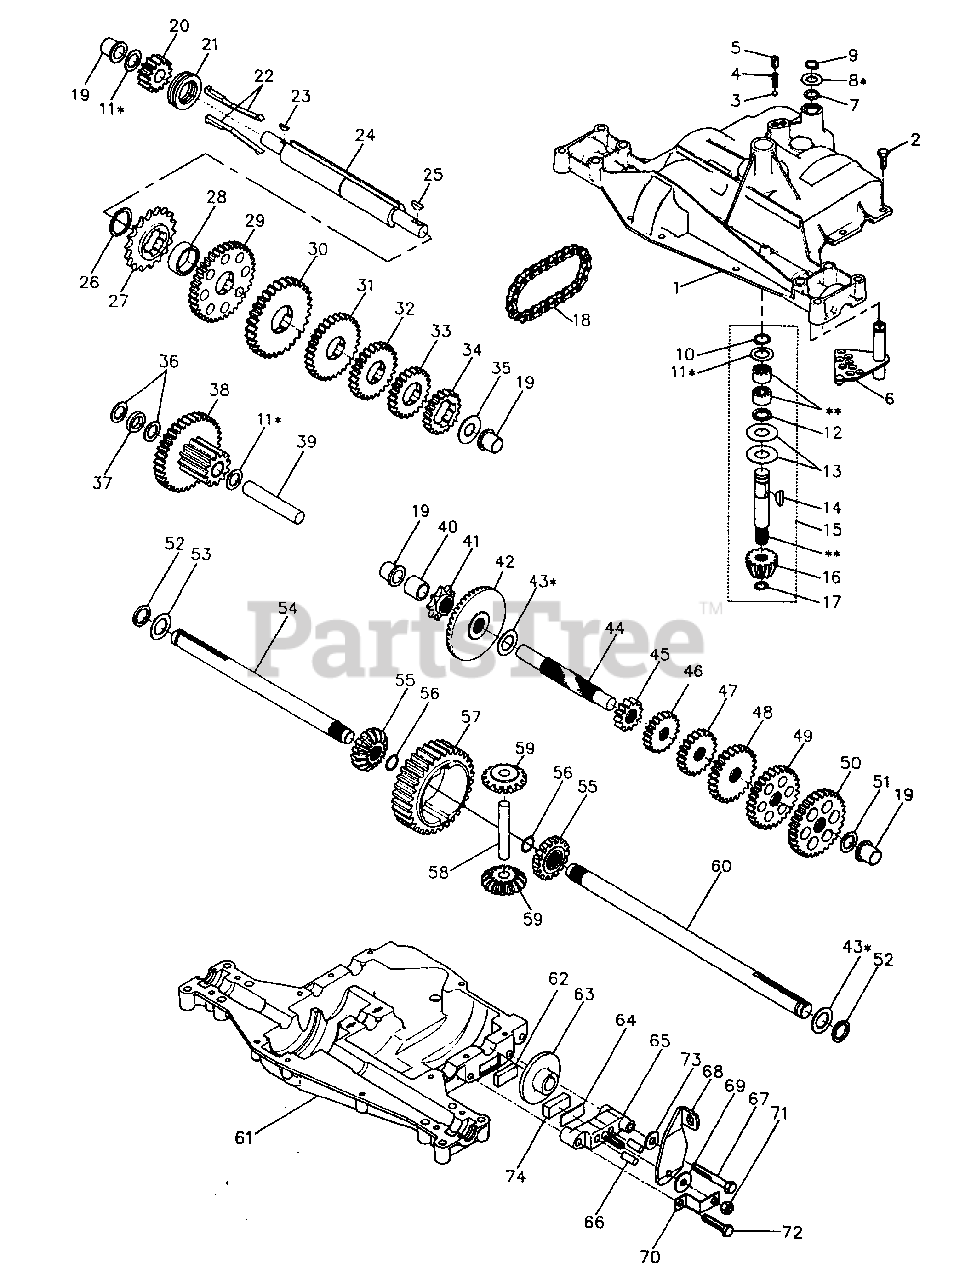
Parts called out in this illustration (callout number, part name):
1	Housing, Upper (AYP part number)
2	Screw, Tapping, Large 1/4-20 x .734 (AYP part number)
3	Ball, Detent (AYP part number)
4	Spring, Detent (AYP part number)
5	Screw, Set (AYP part number)
6	Shifter Assembly (AYP part number)
7	O-Ring (AYP part number)
8	Washer, Plain .505 x .942 x .006 (AYP part number)
8	Washer, Plain .505 x .942 x .010 (AYP part number)
8	Washer, Plain .505 x .942 x .015 (AYP part number)
8	Washer, Plain .505 x .942 x .020 (AYP part number)
8	Washer, Plain .505 x .942 x .026 (AYP part number)
8	Washer, Plain .505 x .942 x .030 (AYP part number)
8	Washer, Plain .505 x .942 x .040 (AYP part number)
9	Ring, Retaining (AYP part number)
10	Ring, Retaining (AYP part number)
11	Washer, Plain .632 x 1.00 x .010 (AYP part number)
11	Washer, Plain .632 x 1.00 x .020 (AYP part number)
11	Washer, Plain .632 x 1.00 x .026 (AYP part number)
11	Washer, Plain .632 x 1.00 x .031 (AYP part number)
11	Washer, Plain .632 x 1.00 x .036 (AYP part number)
11	Washer, Plain .632 x 1.00 x .041 (AYP part number)
11	Washer, Plain .632 x 1.00 x .046 (AYP part number)
11	Washer, Plain .632 x 1.00 x .050 (AYP part number)
11	Washer, Plain .632 x 1.00 x .060 (AYP part number)
11	Washer, Plain .632 x 1.00 x .082
12	O-Ring (AYP part number)
13	Washer, Plain .632 x 1.38 x .046 (AYP part number)
14	Key, Woodruff, #9 (AYP part number)
15	Kit, Input Shaft Assembly
16	Pinion, Bevel, 14 Teeth (AYP part number)
17	Ring, Retaining (AYP part number)
18	Chain, 24 Pitches (AYP part number)
19	Bearing, Flange (AYP part number)
20	Gear, Spur, 14 Teeth (AYP part number)
21	Collar, Clutch (AYP part number)
22	Key, Clutch (AYP part number)
23	Key, Woodruff, #3 (AYP part number)
24	Shaft, Intermediate (AYP part number)
25	Key, Woodruff, #61 (AYP part number)
26	Ring, Retaining (AYP part number)
27	Sprocket, 18 Teeth (AYP part number)
28	Spacer (AYP part number)
29	Gear, Spur, 37 Teeth (AYP part number)
30	Gear, Spur, 35 Teeth (AYP part number)
31	Gear, Spur, 30 Teeth (AYP part number)
32	Gear, Spur, 25 Teeth (AYP part number)
33	Gear, Spur, 22 Teeth (AYP part number)
34	Gear, Spur, 19 Teeth (AYP part number)
35	Washer, Plain .640 x 1.37 x .061 (AYP part number)
36	Washer, Plain .632 x 1.00 x .026 (AYP part number)
37	Spacer .630 x 1.00 x .169 (AYP part number)
38	Assembly, Gear, Combination of 12 Teeth and 35 Teeth (AYP part number)
39	Shaft, Idler (AYP part number)
40	Spacer .635 x .875 x .755 (AYP part number)
41	Sprocket, 9 Teeth (AYP part number)
42	Gear, Bevel, 42 Teeth (AYP part number)
43	Washer, Plain .758 x 1.12 x .010 (AYP part number)
43	Washer, Plain .758 x 1.12 x .015 (AYP part number)
43	Washer, Plain .758 x 1.12 x .020 (AYP part number)
43	Washer, Plain .758 x 1.12 x .025 (AYP part number)
43	Washer, Plain .758 x 1.25 x .020 (AYP part number)
43	Washer, Plain .758 x 1.25 x .025 (AYP part number)
43	Washer, Plain .758 x 1.25 x .031 (AYP part number)
43	Washer, Plain .758 x 1.25 x .035
43	Washer, Plain .758 x 1.25 x .040 (AYP part number)
43	Washer, Plain .758 x 1.25 x .045 (AYP part number)
43	Washer, Plain .758 x 1.25 x .050 (AYP part number)
43	Washer, Plain .758 x 1.25 x .055 (AYP part number)
43	Washer, Plain .758 x 1.25 x .062 (AYP part number)
44	Shaft, Drive (AYP part number)
45	Gear, Spur, 12 Teeth (AYP part number)
46	Gear, Spur, 15 Teeth (AYP part number)
47	Gear, Spur, 20 Teeth (AYP part number)
48	Gear, Spur, 25 Teeth (AYP part number)
49	Gear, Spur, 28 Teeth (AYP part number)
50	Gear, Spur, 31 Teeth (AYP part number)
51	Washer, Plain .632 x 1.00 x .060 (AYP part number)
52	Seal, Felt (AYP part number)
53	Washer, Plain .758 x 1.25 x .062 (AYP part number)
54	Axle, Left Hand (AYP part number)
55	Gear, Miter, 15 Teeth (AYP part number)
56	Ring, Retaining (AYP part number)
57	Gear, Spur, 32 Teeth (AYP part number)
58	Shaft, Cross (AYP part number)
59	Gear, Miter, 15 Teeth (AYP part number)
60	Axle, Right Hand (AYP part number)
61	Housing, Lower (AYP part number)
62	Puck, Friction (AYP part number)
63	Disc, Brake (AYP part number)
64	Spacer (AYP part number)
65	Jaw, Brake (AYP part number)
66	Pin, Dowel (AYP part number)
67	Screw, Tapping, Large 5/16-18 x 2.25 (AYP part number)
68	Lever, Actuating (AYP part number)
69	Washer, Plain .321 x 1.00 x .055 (AYP part number)
70	Bracket, Anti-Rotation (AYP part number)
71	Locknut 5/16-24 (AYP part number)
72	Screw, Tapping, Large 5/16-18 x 1.44 (AYP part number)
73	Washer, Plain .343 x .81 x .059 (AYP part number)
74	Puck, Friction (AYP part number)
75	Grease (AYP part number)
